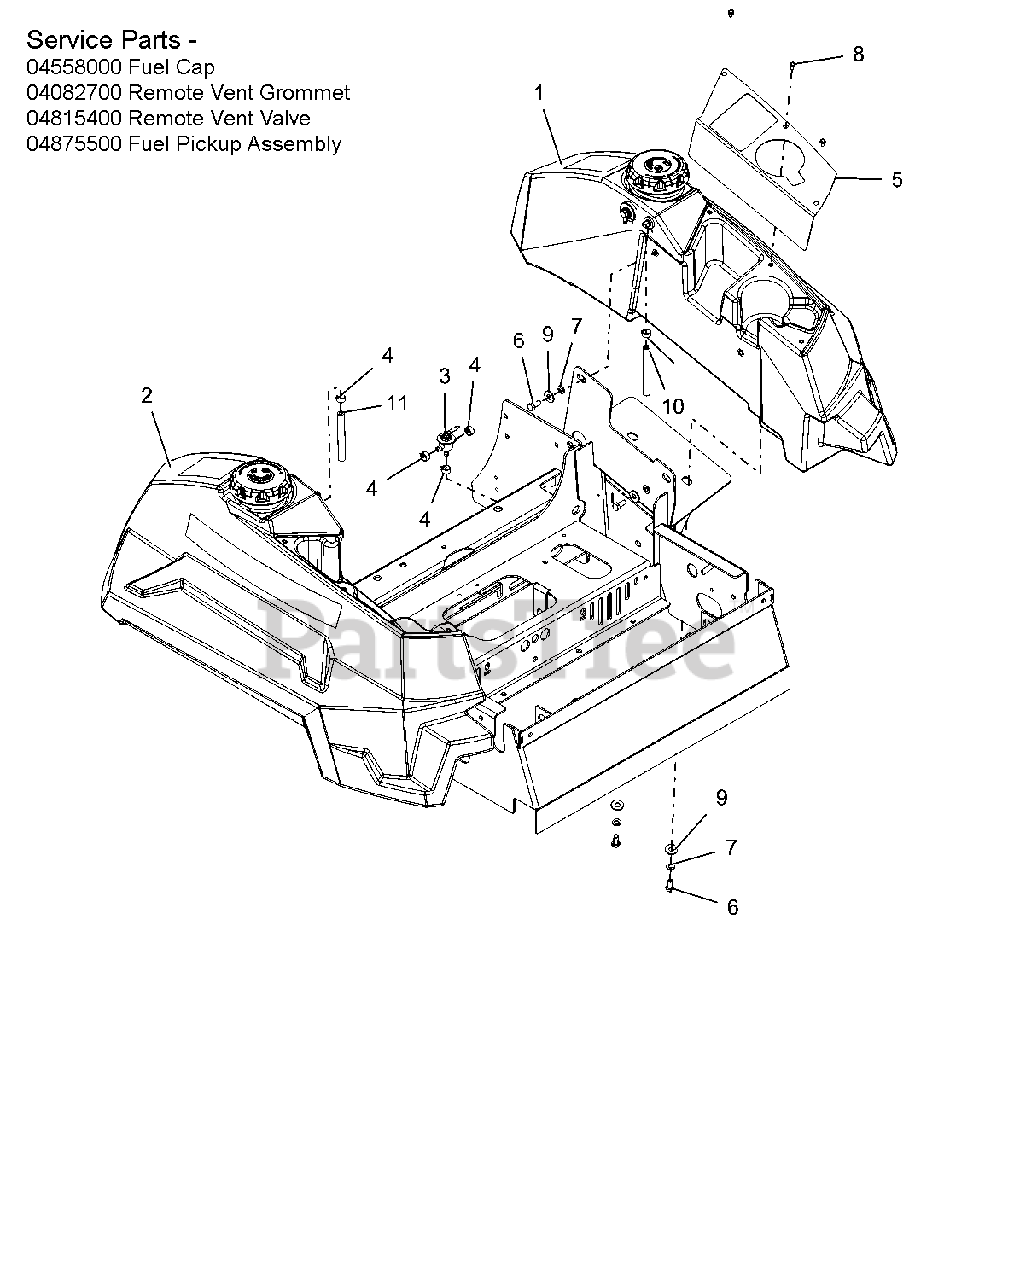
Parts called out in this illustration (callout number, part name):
1	ASSY-LH, PT200 FUEL TANK
1	REMOTE VENT GROMMET
1	FUEL CAP
1	REMOTE VENT VALVE
1	FUEL PICKUP ASSEMBLY
2	ASSY-RH, PT200, FUEL TANK
2	FUEL CAP
2	REMOTE VENT VALVE
2	FUEL PICKUP ASSEMBLY
2	REMOTE VENT GROMMET
3	VALVE, FUEL
4	CLAMP, FUEL LINE
5	PLATE, CUP HOLDER/POCKET (RED)
6	BLT-HEX .31-18X.75 GR5 YWZC
7	WSHR-LK .31X.078 REG YWZC
8	SCR-MCH 10-24X.38 HWHSTAINLESS
9	WSHR-FL-STL.38X.875X.083 YWZC
10	.25 LOW-PERM GAS HOSE 19.00" LG - LH TANK TO VALVE
11	.25 LOW-PERM GAS HOSE 32.00" LG - LH TANK TO VALVE
